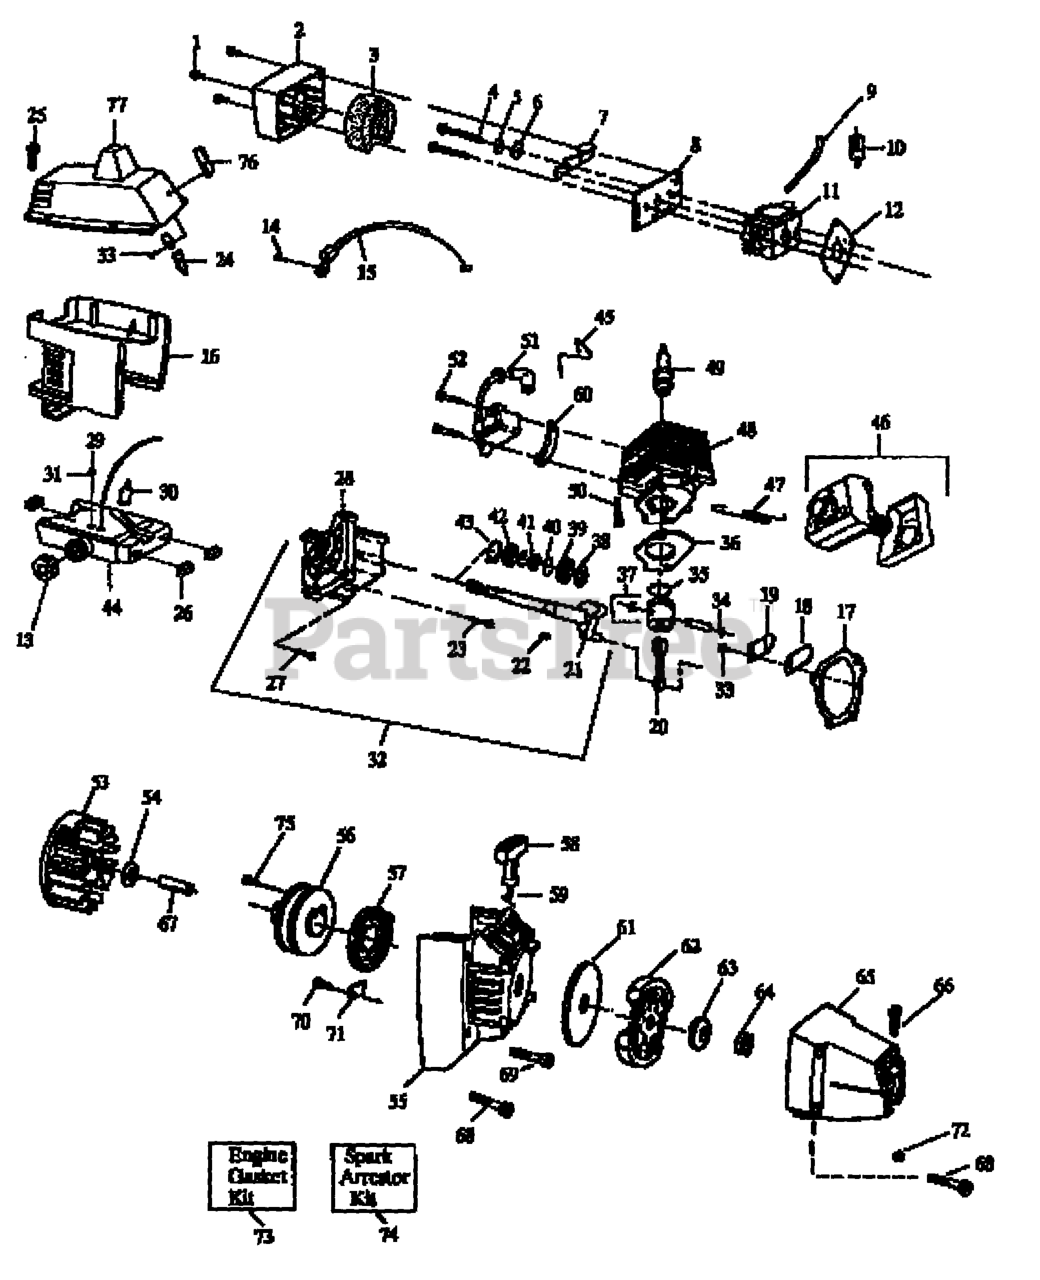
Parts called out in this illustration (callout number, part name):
1	SCREW-10-24 X 13/16
2	COVER
3	AIR FILTER
5	SPACER-CHOKE
7	Choke Shutter
8	Air Filter Plate
9	FUEL LINE KIT
10	FUEL FILTER
11	CARBURETOR (WA-199)
12	GASKET-CARB
13	FUEL CAP ASSY.
14	SCREW 8-16 X 9/16 (PLAS
15	THROTTLE CABLE
16	SHROUD
17	GASKET-C'CASE/SHROUD
18	VALVE-REED
20	ASS'Y-CONNECTING ROD
21	ASSY-CRANKSHAFT
22	KEY-FLYWHEEL
23	SCREW-10-24 X 1" (TAP.)
24	Switch Retainer
25	SCREW-10-14 X 13/16 (PL
27	SCREW 1/4-20 X 7/8 (TAP
28	Crankcase Ass'y.
29	VALVE-CHECK (DUCKBILL)
32	ASSY-C'CASE & C'SHAFT
33	SCREW-6-19X5/16PLAST PA
34	WRIST PIN RET.
35	Piston Ring
36	GASKET-CYL W/ADHESIVE
37	Piston Kit
38	SPACER-BEARING
39	Inner Bearing
41	SEAL-CRANKSHAFT
42	Outer Bearing
43	RING-RETAINING (SHAFT)
44	Fuel Tank Ass'y.
45	Switch Wire Form
46	GASKET-INSULATOR
47	SPRING
48	Cylinder
49	Spark Plug
50	SCREW 1/4-20 X 7/8
52	Screw
53	ASSY-FLYWHEEL
54	WASHER
55	FAN HSG. ASSY.
56	STARTER PULLEY
57	SPRING-STARTER
58	STARTER HANDLE 36/41
59	STARTER ROPE
60	SPACER-IGNITION MODULE
61	WASHER-CLUTCH
62	ATTACHMENT KIT
63	WASHER-BELLEVILLE
65	CLUTCH HSG.
66	SCREW-10-24 X 1-3/8 (UN
67	SPACER-CLUTCH
69	SCREW-10-24X1-3/8-TAPTI
70	SCREW-10-16 X 1/2 HI-LO
72	LOCKNUT-HEX 10-24
73	GASKET SET
74	Spark Arrestor Kit
75	SCREW-6-19X9/32 PAN/SEM
77	CYL. COVER
